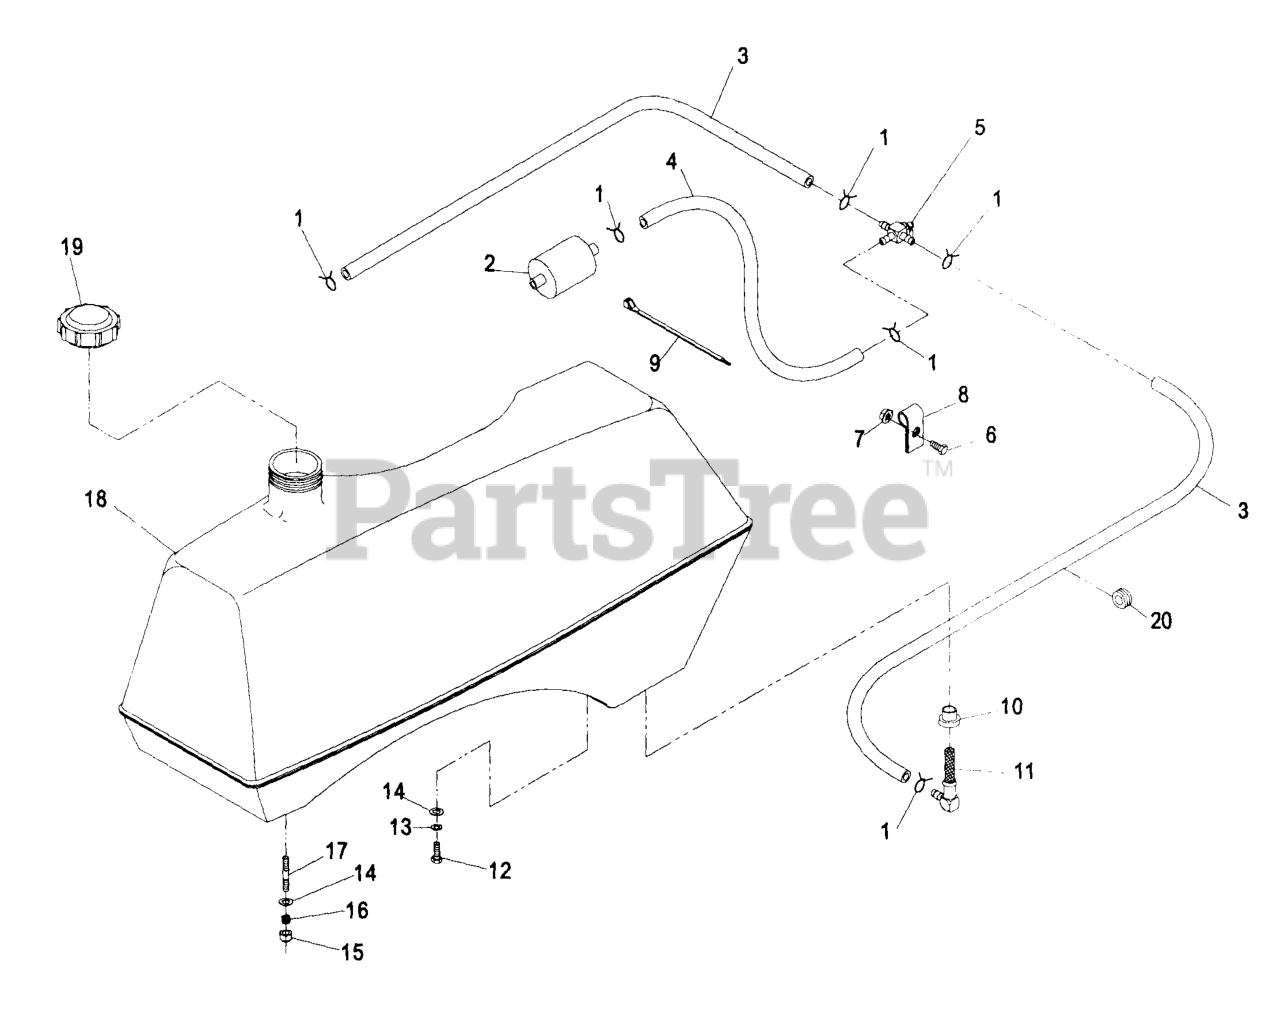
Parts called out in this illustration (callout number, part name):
2	Kohler Fuel Filter
5	VALVE-FUEL
8	CLIP-LOOM
9	TIE-PLASTIC
11	ELBOW-TANK, FUEL
13	WASHER-LOCK
16	SPRING-TANK, FUEL
17	STUD
19	CAP-FUEL
20	GROMMET
